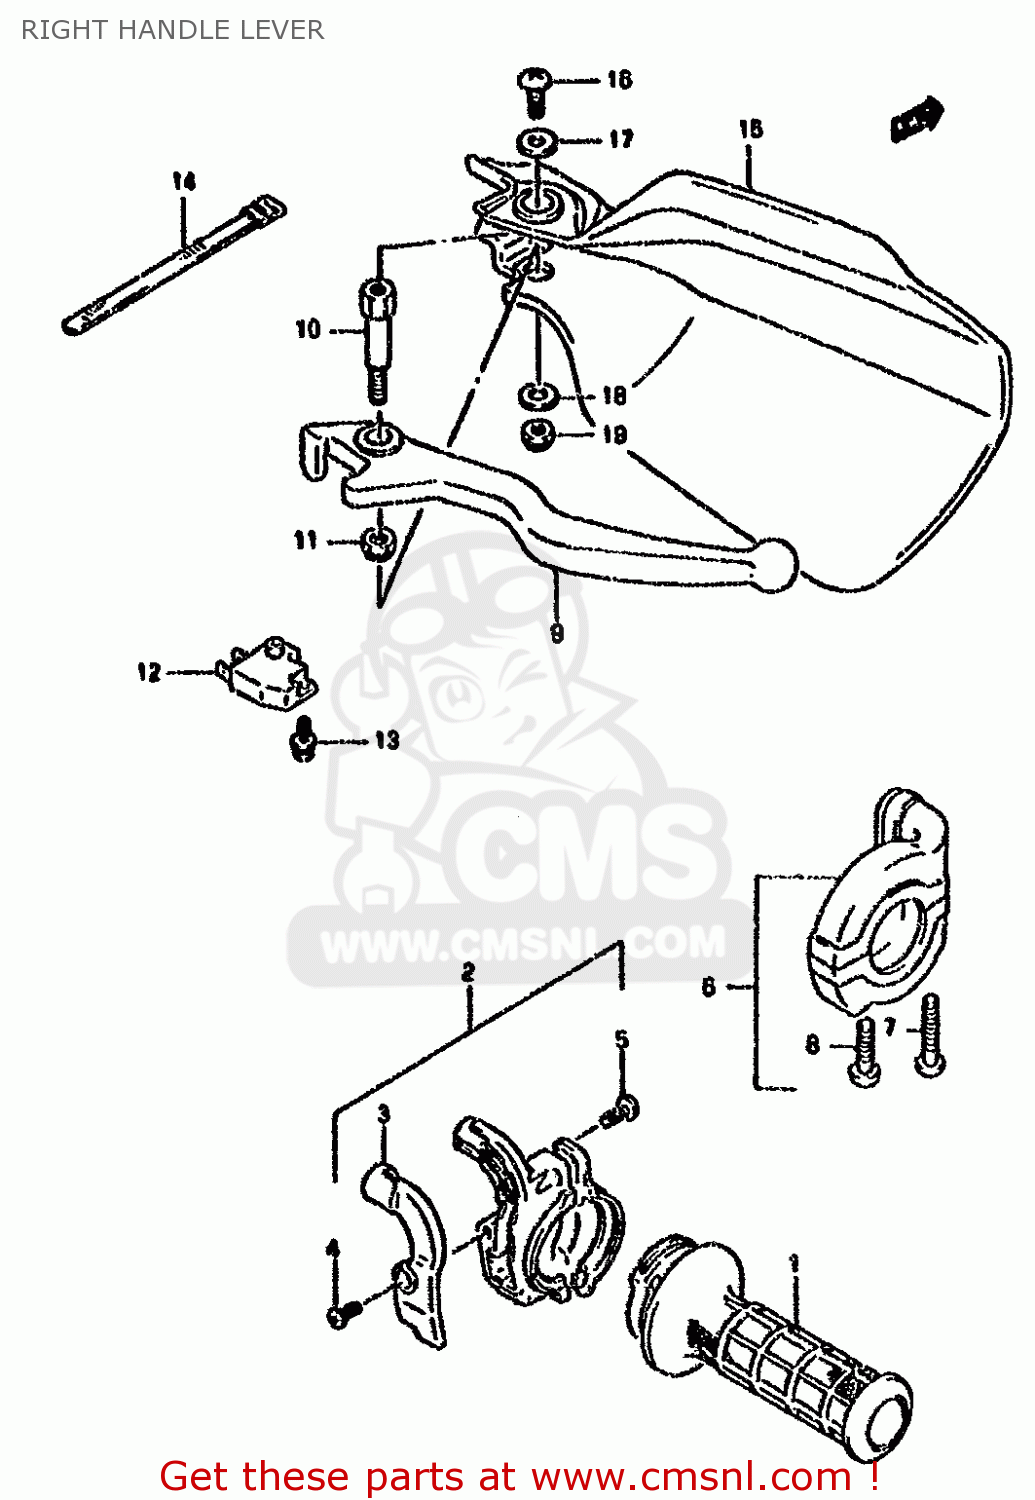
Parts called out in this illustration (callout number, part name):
1	GRIP,THROTTLE
2	CASE ASSEMBLY,THROTTLE
3	COVER,THROTTLE CASE
4	SCREW 4X10
5	SCREW
6	CASE ASSY,THROTTLE
7	SCREW(5X25)
8	SCREW 5X20
9	LEVER,BRAKE
10	BOLT,BRAKE LEVER PIVOT
11	NUT
12	SWITCH ASSEMBLY,STOP
13	SCREW
14	CLAMP(L:120)
15	COVER,KNUCKLE,R
16	SCREW
17	WASHER (5.5X16X1.2)
18	WASHER (6.5X17X1.6)
19	NUT 6MM
